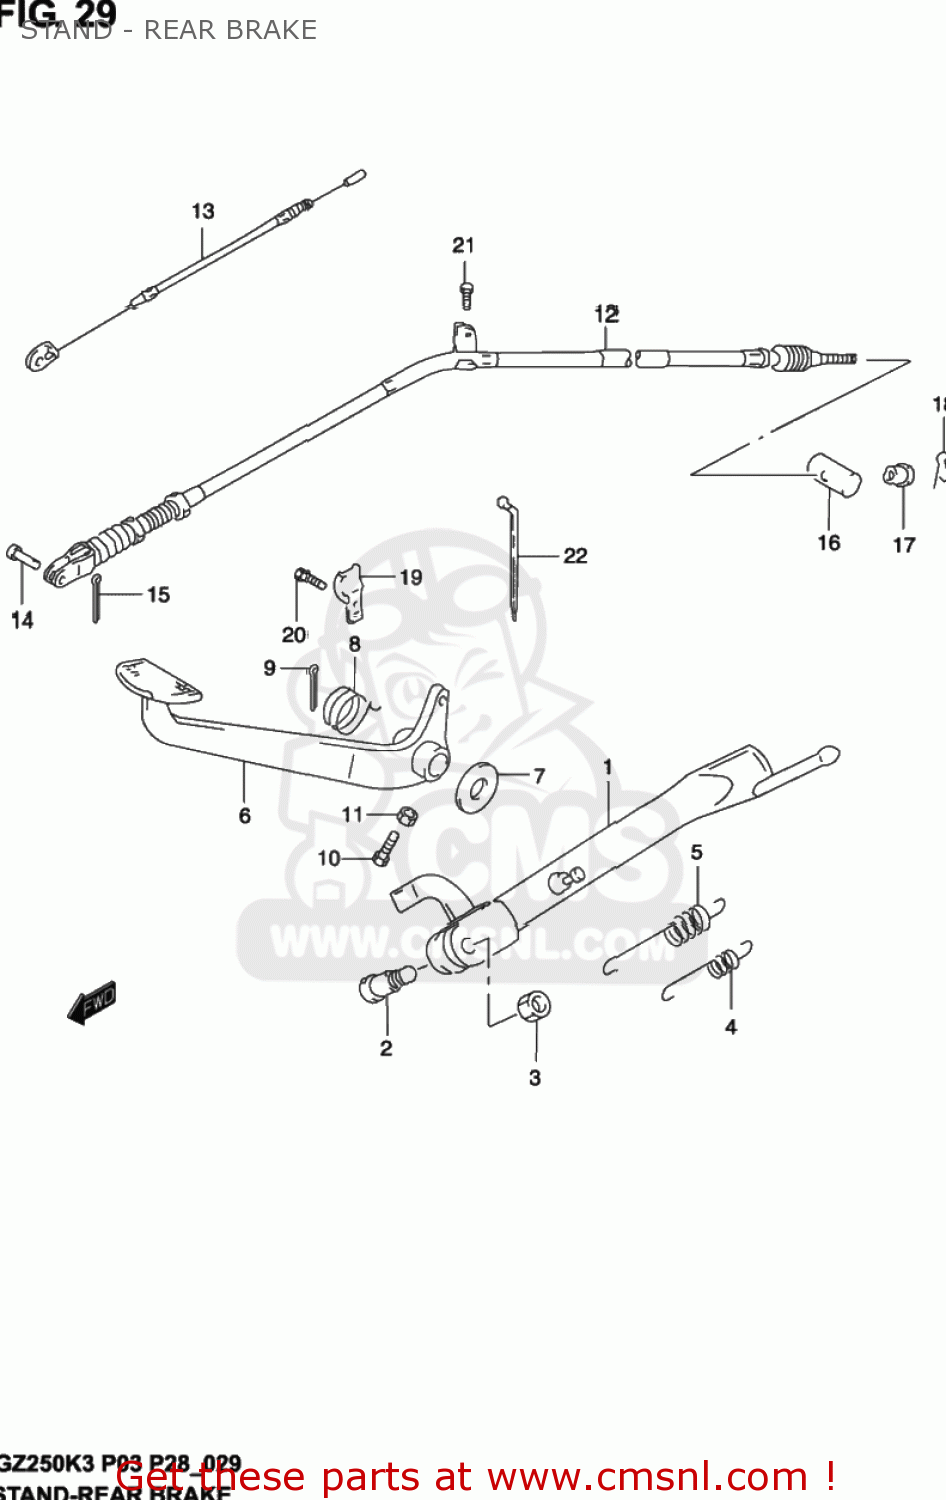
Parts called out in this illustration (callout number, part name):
1	STAND,PROP
2	BOLT(10X34)
3	NUT
4	SPRING
5	SPRING
6	PEDAL, BRAKE
7	WASHER(16.5X22X1)
8	SPRING
9	PIN
10	BOLT
11	NUT
12	CABLE,RR BRAKE
13	CABLE,STOP LAMP SWITCH
14	PIN(L:17.5)
15	PIN
16	PIN
17	NUT
18	CLIP
19	GUIDE,RR BRAKE CABLE
20	BOLT
21	BOLT
22	CLAMP(L:145)
